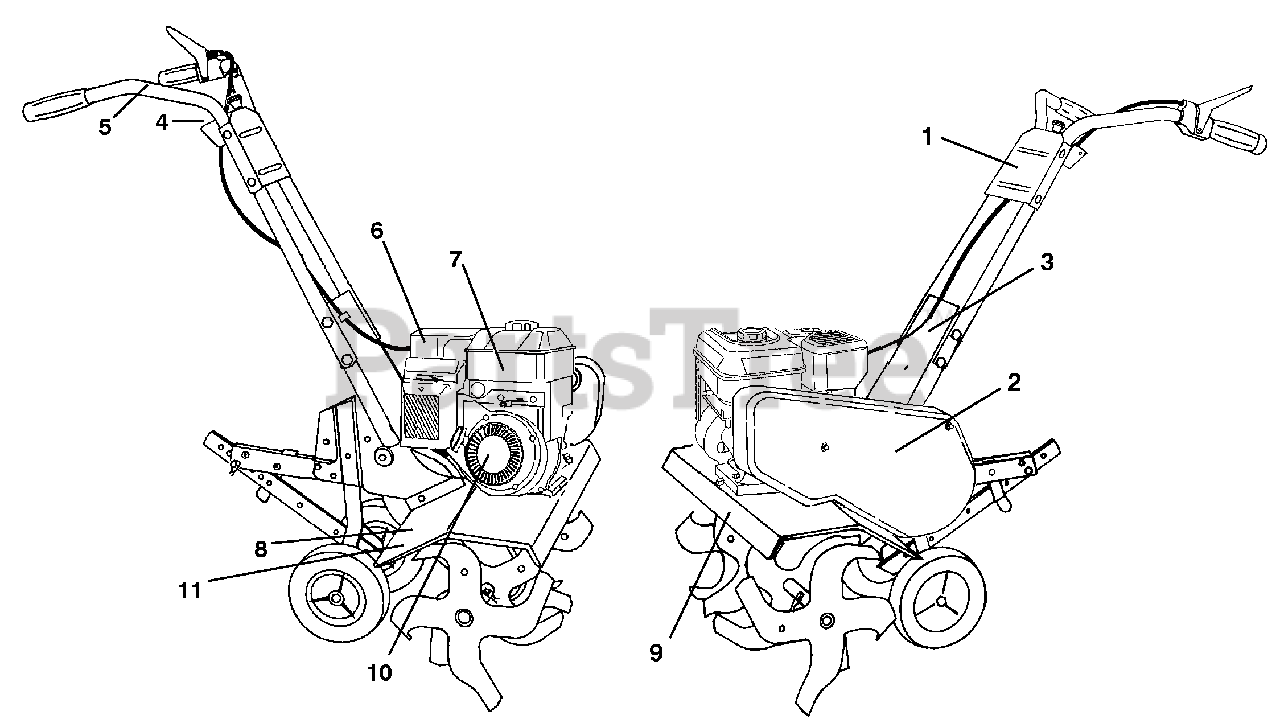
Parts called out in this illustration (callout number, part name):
1	Decal, Poulan Pro
2	Decal, Poulan Pro, 825 Series / 26"
3	Decal, Forward and Reverse
4	Decal, Reverse, Tine Control
5	Decal, Hand Placement
6	Decal, Engine
7	Decal, OHV, I/C
8	Decal, Warning
9	Decal, Heavy Duty
10	Decal, Rewind Starter
11	Decal, Warning, Rotating Tines
11	Manual, Operator's, English / French
11	Manual, Repair Parts
